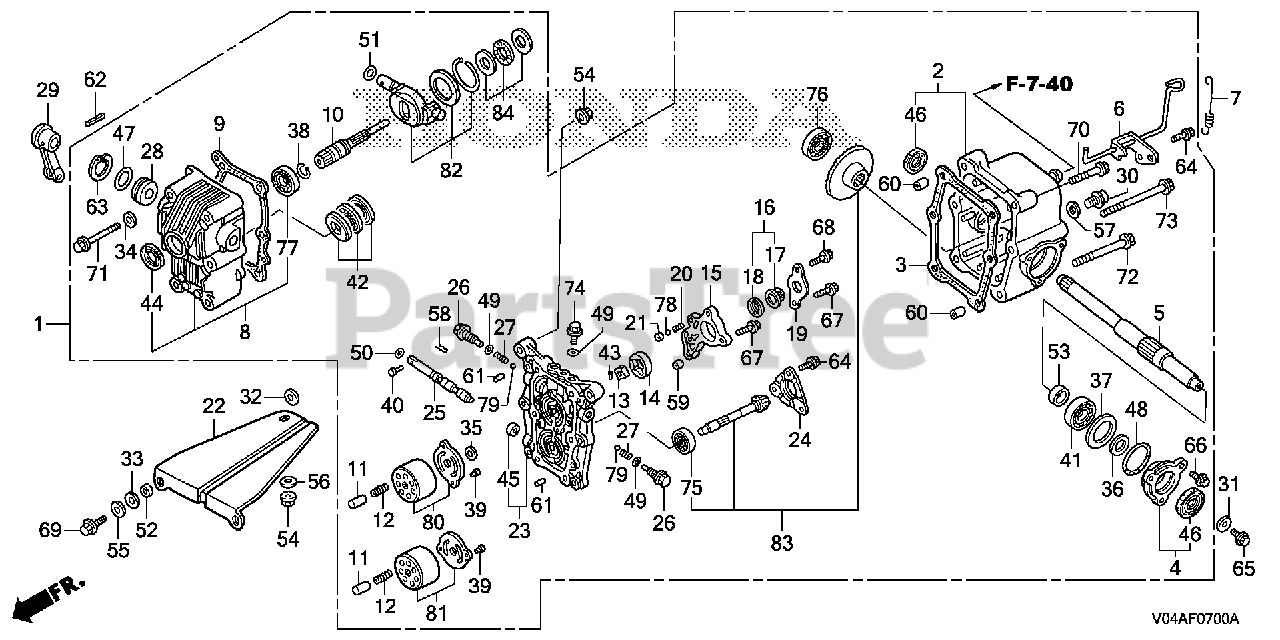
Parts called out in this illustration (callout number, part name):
1	TRANSMISSION ASSY.
2	CASE, RR. TRANSMISSION
3	GASKET, RR. TRANSMISSION CASE
4	HOLDER, OIL SEAL
5	SHAFT, CROSS
6	ARM, NEUTRAL VALVE
7	SPRING, NEUTRAL VALVE
8	CASE, PUMP
9	GASKET, PUMP CASE
10	SHAFT, PUMP
11	PISTON, PUMP (HOLE DEPTH=18MM)
12	SPRING, PISTON (5.8X34.5)
13	ROTOR, TROCHOID
14	VANE, TROCHOID
15	HOUSING, TROCHOID
16	FILTER ASSY., SUCTION
17	FILTER, SUCTION
18	SEAL, RUBBER
19	PLATE, FILTER CAP
20	SPRING, RELIEF VALVE
21	SEAT, RELIEF VALVE
22	PLATE, TRANSMISSION MOUNTING
23	PLATE, DISTRIBUTOR
24	HOLDER, BEARING
25	SPOOL, NEUTRAL VALVE
26	BOLT, CHECK VALVE
27	SPRING, CHECK VALVE
28	BUSH, CONTROL BOWL (B)
29	ARM, CLUTCH
30	BOLT, PLUG
32	WASHER (8MM)
33	WASHER, WAVE (12MM)
34	WASHER, SEALING (9X16X1.5)
35	WASHER, THRUST (8MM)
36	WASHER, PLAIN (15MM)
37	SHIM A, BEVEL GEAR (1.5MM)
37	SHIM B, BEVEL GEAR (1.55MM)
37	SHIM C, BEVEL GEAR (1.6MM)
37	SHIM D, BEVEL GEAR (1.65MM)
37	SHIM E, BEVEL GEAR (1.7MM)
37	SHIM F, BEVEL GEAR (1.75MM)
38	CLIP, BEARING
39	PIN, DOWEL (3X5.8)
40	PIN, NEUTRAL VALVE
41	BEARING, RADIAL BALL (6904) (NTN)
42	BEARING, THRUST BALL (51204)
43	ROLLER (2.5X11.8)
44	OIL SEAL (17X30X5) (NOK)
45	DUST SEAL (9X15X5)
46	OIL SEAL (15X28X7)
47	O-RING (25X2.4)
48	O-RING (34.6X1.9)
49	O-RING (11X1.9)
50	O-RING (5.8X1.9)
51	O-RING (11.8X1.9)
52	COLLAR, TRANSMISSION MOUNT (8X12X4.7)
53	COLLAR, BEVEL GEAR
54	NUT, FLANGE (8MM)
55	WASHER, PLAIN (8MM)
56	WASHER, PLAIN (8MM)
57	WASHER, DRAIN PLUG (14MM)
58	PIN, LOCK (4MM)
59	PIN, DOWEL (8X10)
60	PIN, DOWEL (10X12)
61	PIN, DOWEL (5X8)
62	PIN, SPRING (4X28)
63	CIRCLIP (INNER) (30MM)
64	BOLT, FLANGE (6X12)
65	BOLT, FLANGE (6X16)
66	BOLT, FLANGE (6X16)
67	BOLT, FLANGE (6X25)
68	BOLT, FLANGE (6X32)
69	BOLT, FLANGE (8X40)
70	BOLT, FLANGE (8X45)
71	BOLT, FLANGE (8X65)
72	BOLT, FLANGE (8X70)
73	BOLT, FLANGE (8X90)
74	BOLT, FLANGE (10X16)
75	BEARING, RADIAL BALL (6001)
76	BEARING, RADIAL BALL (6002)
77	BEARING, RADIAL BALL (6003)
78	BALL, STEEL (#6) (3/16)
79	BALL, STEEL (#8) (1/4)
80	PLATE SET, PUMP CYLINDER
81	PLATE SET, MOTOR CYLINDER
82	BOWL SET, CONTROL
83	GEAR SET, MOTOR SHAFT & BEVEL
84	BEARING SET, THRUST NEEDLE
